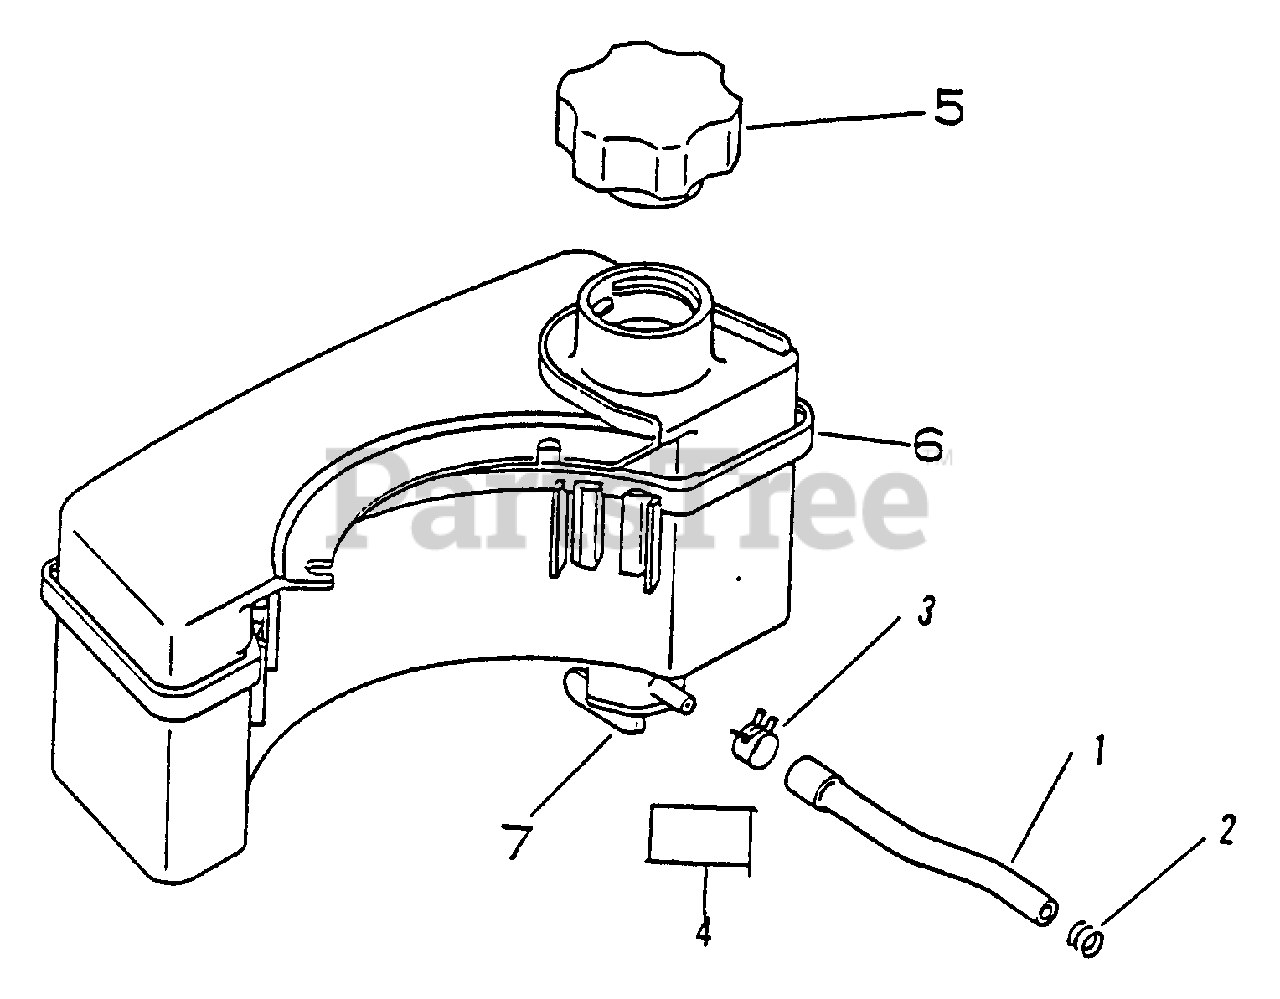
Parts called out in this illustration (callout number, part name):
1	PIPE, FUEL
2	CLIP, PIPE
3	CLIP, PIPE
4	LABEL, FUEL COCK
5	CAP
6	FUEL TANK ASSY
7	FUEL VALVE ASSY
7	VALVE KIT, FUEL W/O WASHER
